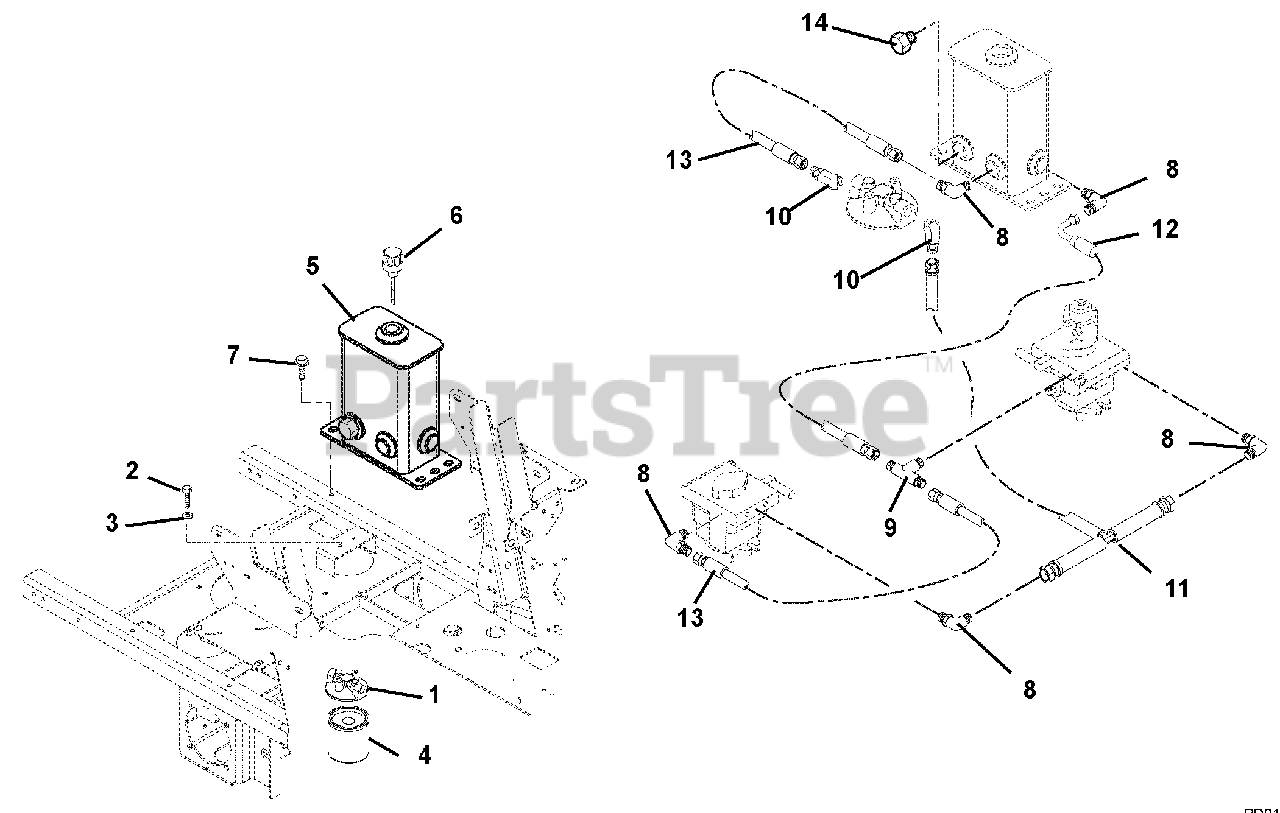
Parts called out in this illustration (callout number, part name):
1	Head, Filter
2	Bolt, Hex .25-20 x .50 Grade 5
3	Washer, Locking .25 x .062
4	Oil Filter
5	Weldment, Hydraulic Tank
6	Hydraulic Tank Dipstick
7	Screw, Tapping .38-16 x .75 Hex Washer Head
8	Fitting, Hydraulic, 90 Degree Elbow, Steel M8F-M80
9	Fitting, Hydraulic Tee M80-M80-M80
10	Fitting, Hydraulic 45° M80-M120
11	Hose, Tee Assembly, .50
12	Hose, Hydraulic
13	Hose, Hydraulic
14	Plug, Hex, .75-16 O-Ring
